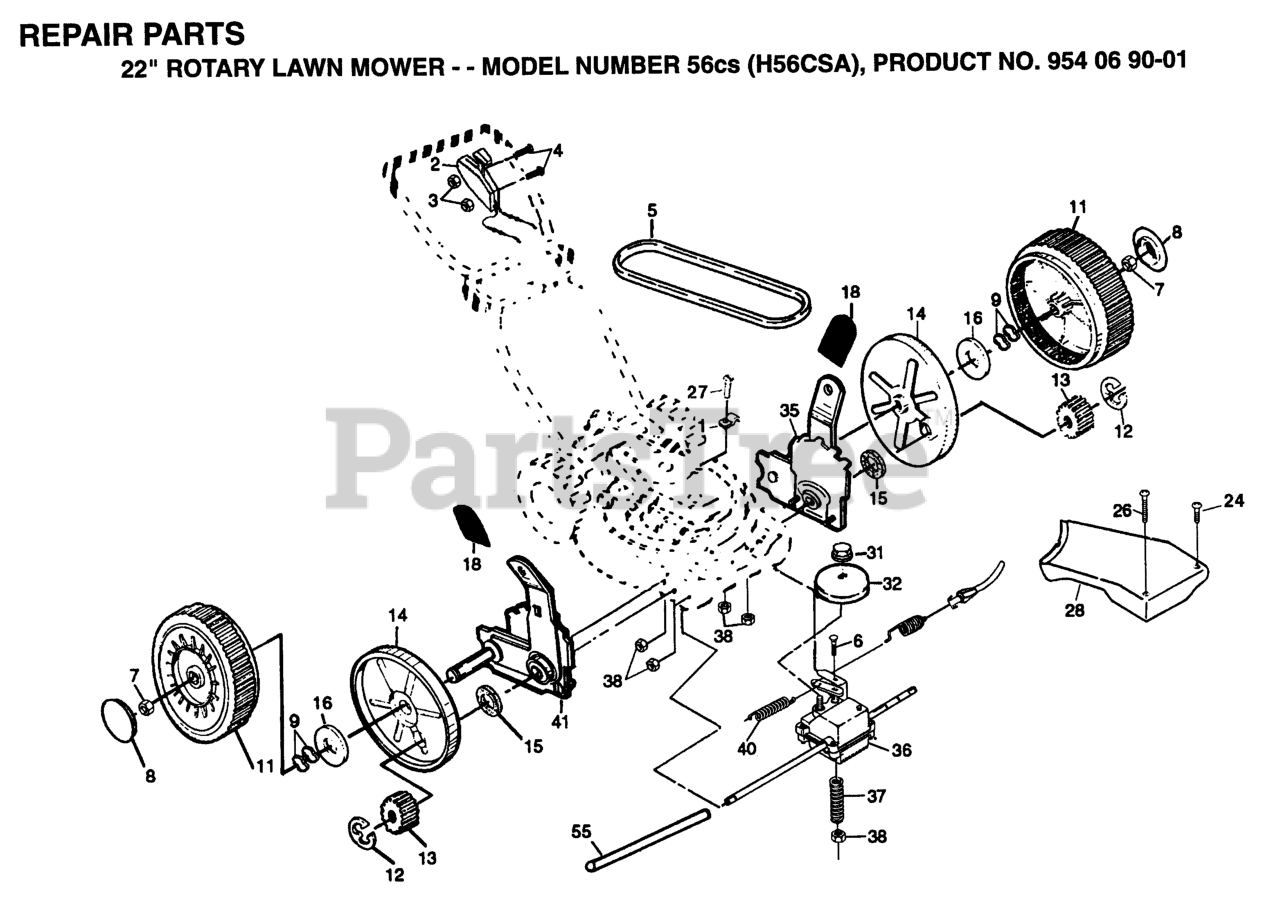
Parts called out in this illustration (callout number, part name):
1	GUIDE CLIP PM
3	NUT
4	SCREW**
5	BELT DRIVE
7	HEX FLANGE LOCKNT
8	CAP.HUB.BLACK.WALK
9	WAVE WASHER
11	WHEEL ASSEMBLY
12	E-RING 7/16 RE
13	PINION GEAR
14	DUST SHROUD PM
16	WASHER FLUT
18	SELECTOR KNOB
24	SCREW
27	TAPPING SCREW
28	DRIVE COVER
31	FLANGED LOCKNUT 3/8-16 ZINC
32	PULLEY
37	SPRING.EXTENSION
38	NUT
55	DRV SHAFT TUBE PM
